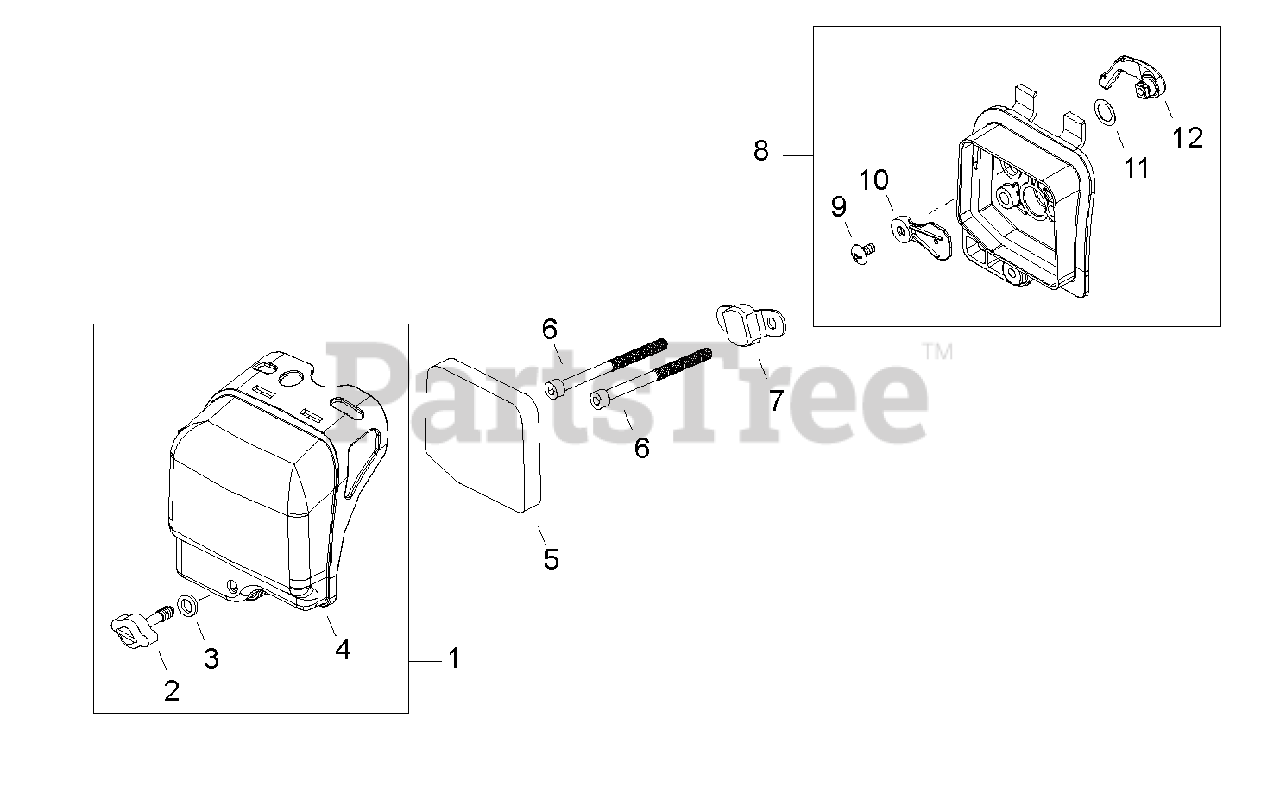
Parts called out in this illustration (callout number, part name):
1	AIR FILTER COVER ASSY
2	THUMBSCREW
3	WASHER - VYNYL
4	COVER, AIR FILTER
5	FILTER, AIR
6	SCREW - 5X60
7	PLATE, PREVENT
8	CASE, AIR FILTER
9	SCREW - 4X12
10	PLATE, CHOKE
11	WASHER - SPRING
12	LEVER, CHOKE
